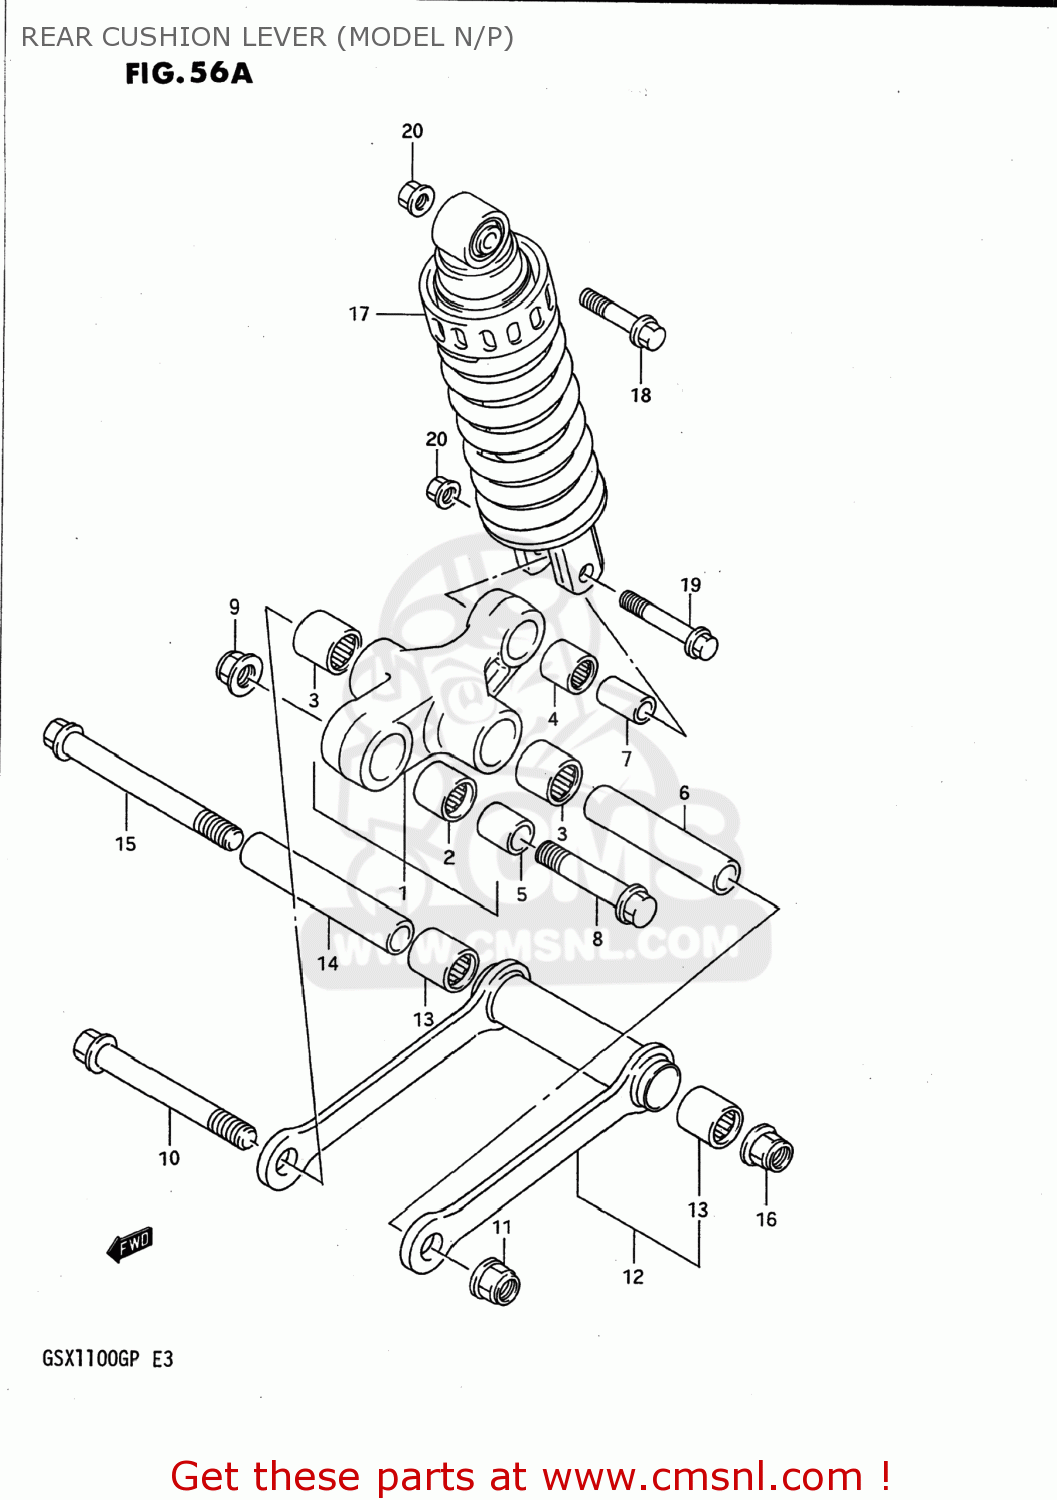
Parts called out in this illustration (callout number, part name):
1	LEVER SET,RR CUSHION
2	BEARING(20X27X32)
3	BEARING(20X27X23.5)
4	BEARING(17X24X26)
5	SPACER(14X20X34)
6	SPACER(14X20X99)
7	SPACER,REAR CUSHION LEVER
8	BOLT(14X66)
9	NUT 14MM
10	BOLT(14X129)
11	NUT 14MM
12	ROD SET,REAR CUSHION,LEFT
13	BEARING(20X27X23.5)
14	SPACER (14X20X129)
15	BOLT(14X159)
16	NUT 14MM
17	ABSORBER ASSY,RR SHOCK
18	BOLT(10X50)
19	BOLT(10X60)
20	NUT 10MM
